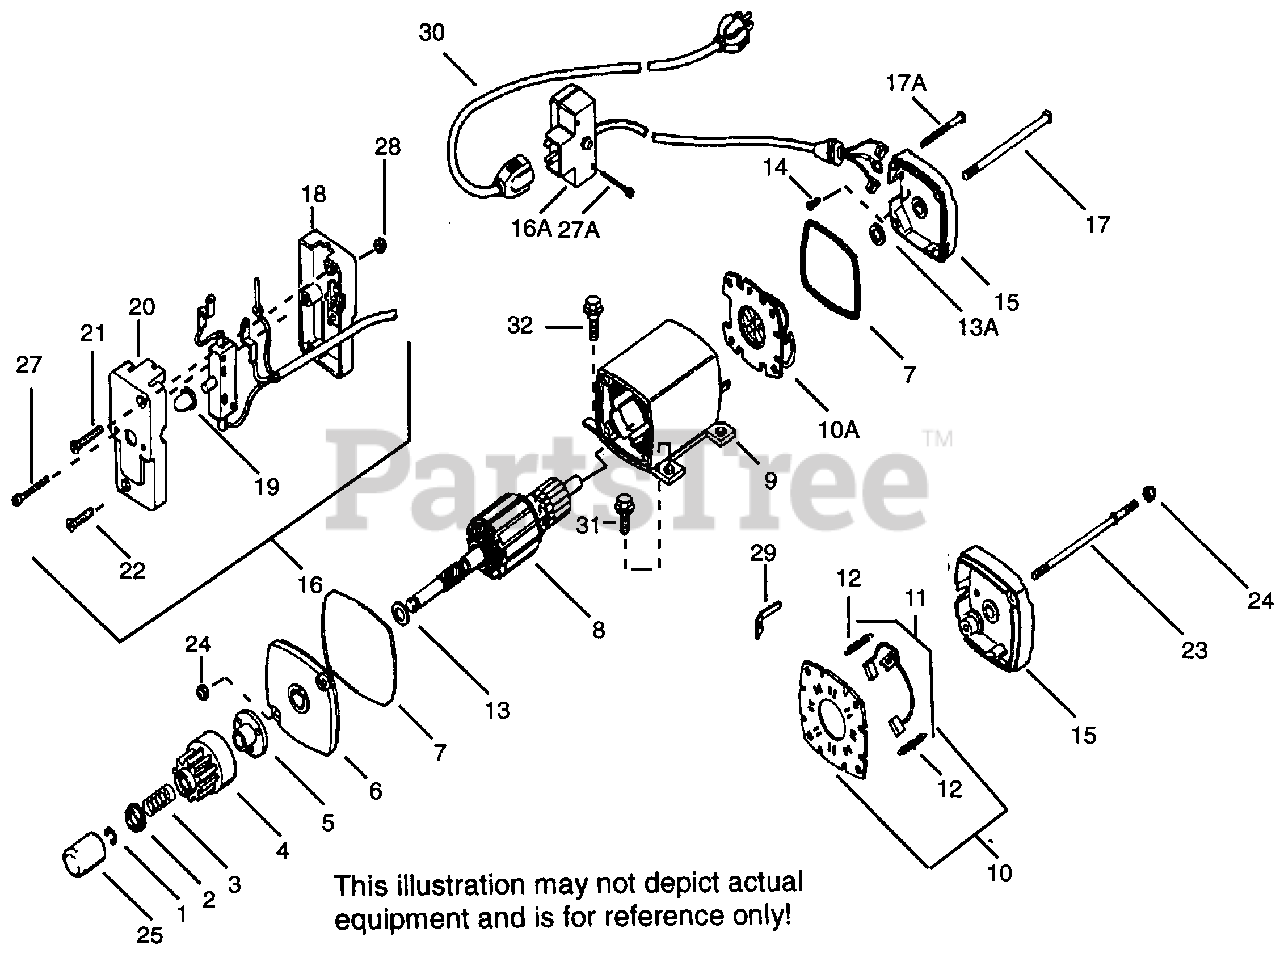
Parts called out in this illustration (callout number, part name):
1	Retainer Ring
2	Spring Retainer
3	Anti-drift Spring
5	Retainer & Nut (Incl. 1)
6	Drive End Cap Ass'y. (Incl. 7)
7	"O" Ring
8	Armature
9	Housing Ass'y.
10A	Brush Card Ass'y.
13A	Thrust Washer
14	Ground Screw
15	Commutator End Cap Ass'y. (Incl. 7)
16A	Switch Box Ass'y. (Incl. 27A)
17	Case Bolt
17A	Grounding Screw
25	Dust Cover
27A	Screw, 6-32 X 2-1/2"
30	Extension Cord (10'6")
31	Screw, T-30, 1/4-20 x 1/2"
